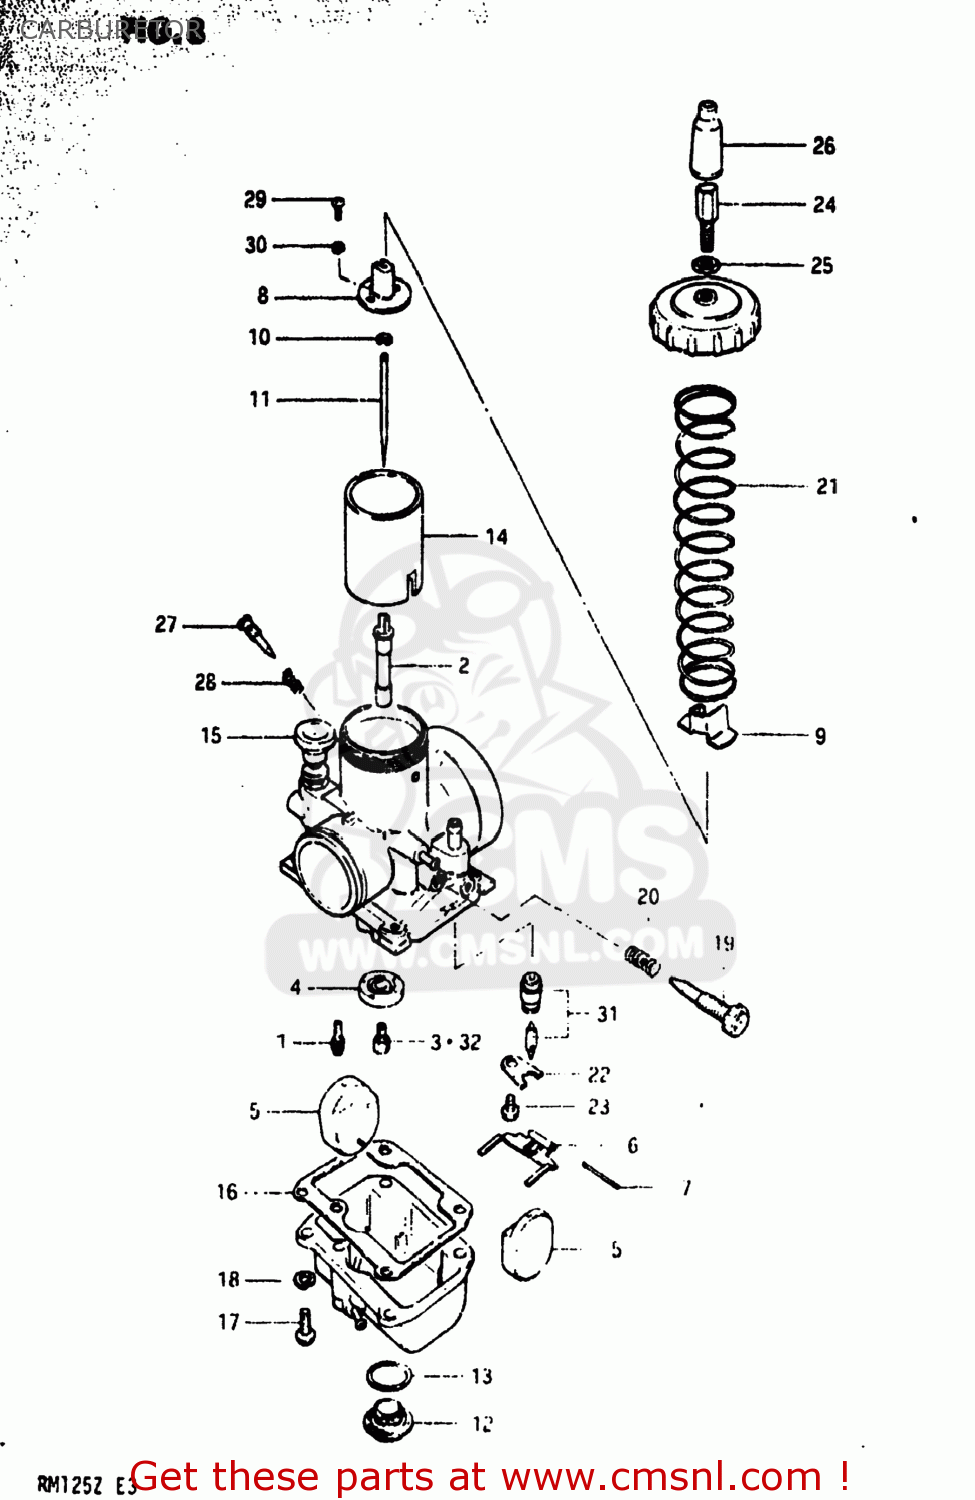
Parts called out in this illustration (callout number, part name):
0	CARBURETOR ASSEMBLY
1	JET
2	JET,NEEDLE
3	JET
4	RING,MAIN JET FIXING
5	FLOAT
6	ARM,FLOAT
7	PIN,FLOAT
8	CONNECTOR
9	COVER,HOLDER
10	CLIP
11	NEEDLE,JET
12	PLUG
13	O RING(D:1.5,ID:19.5)
14	VALVE,THROTTLE
15	VALVE ASSEMBLY,STARTER
16	GASKET,FLOAT CAHMBER (NAS)
17	SCREW
18	LOCK WASHER
19	SCREW,THROTTLE STOP
20	SPRING
21	SPRING,THROTTLE VALVE RETURN
22	PLATE
23	SCREW 4X6
24	ADJUSTER,CABLE
25	NUT
26	CAP,CABLE ADJUSTER
27	SCREW,PILOT AIR
28	SPRING
29	SCREW
30	LOCK WASHER
31	VALVE ASSY,NEEDLE
32	JET
